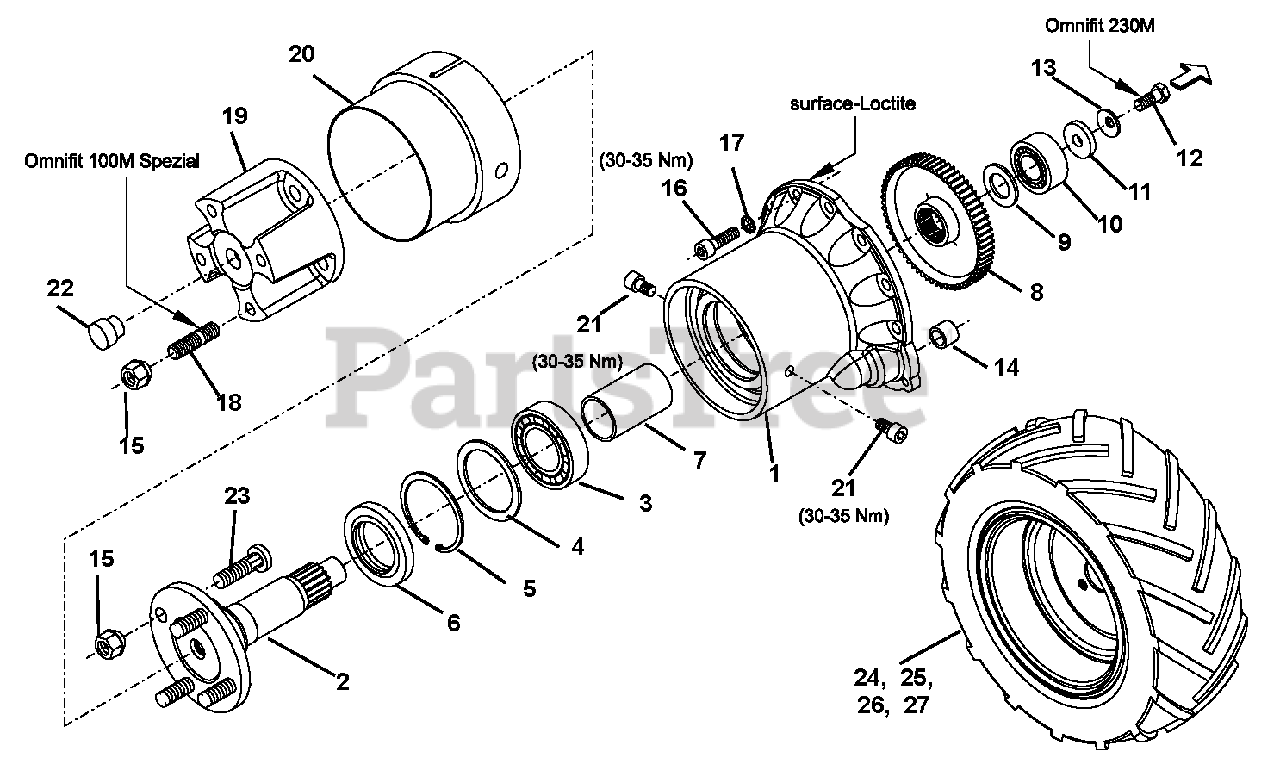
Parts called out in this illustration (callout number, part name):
1	Case, Wheel Bearing
2	Flange, Wheel CPL (Includes Items 2 and 23)
3	Ball Bearing
4	Supporting Ring, D988 63 x 80 x 3
5	Circlip, D472 80 2,50
6	Seal, Oil 50 x 80 x 10 AS
7	Distance Spacer
10	Bearing, Ball, 4205B.TVH
11	Washer, 11,5 x 35 x 6
12	Hexagon Bolt
14	Needle Bearing
16	Screw, D912 M10 x 30
17	Washer, FORM Z 10.2/16.1 x 1.6
18	Bolt, Wheel
19	Intermediate Flange
20	Pipe, Safety
21	Screw, ISO7380 Metric 8 x 12
22	Plug, N559 TL-4-133
23	Wheel Stud M14 x 1.5 x 50
24	Disc Wheel
26	Tyre Tube
